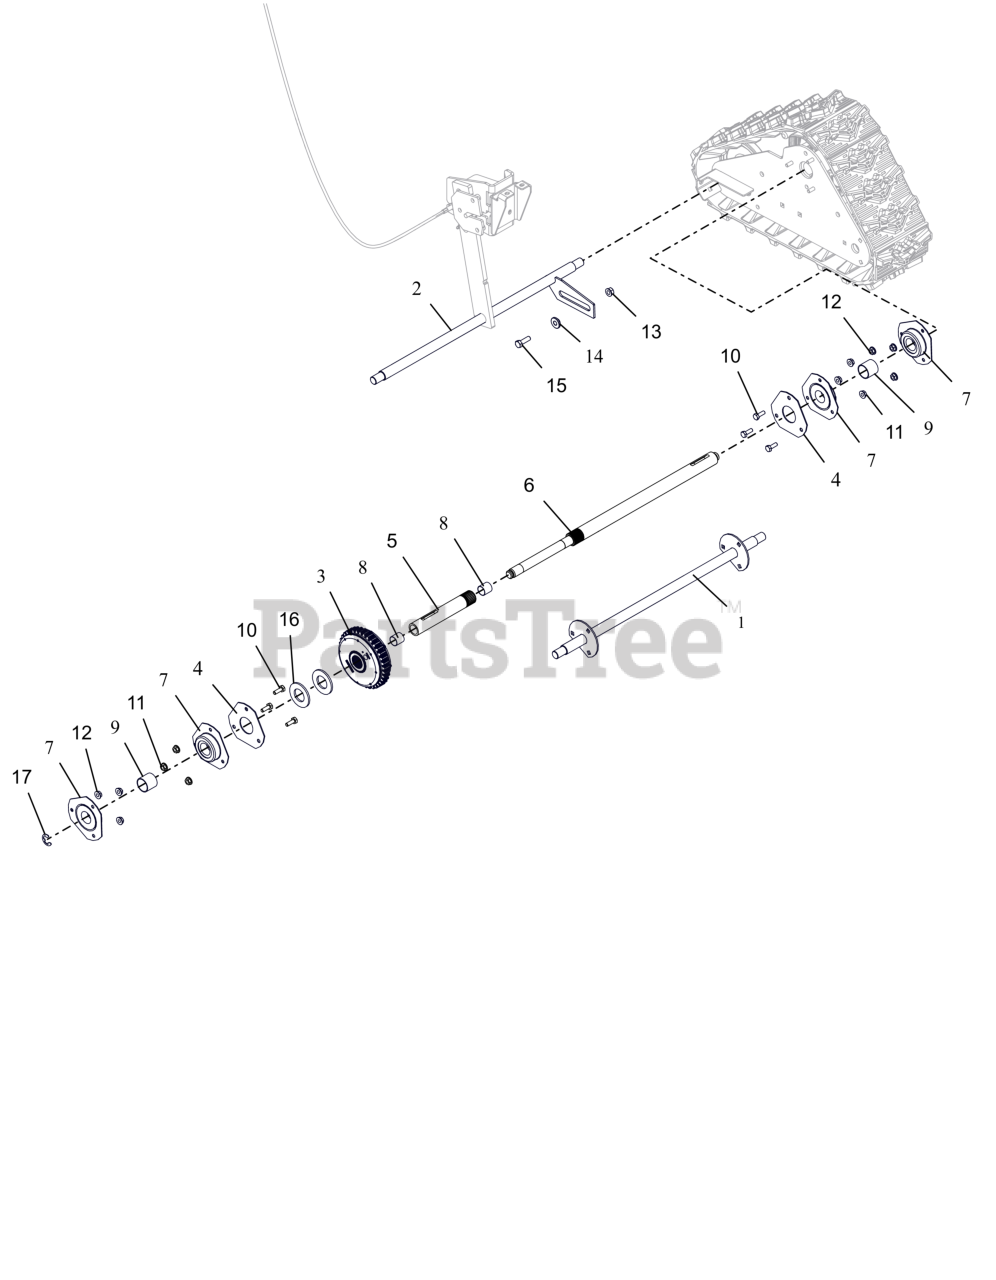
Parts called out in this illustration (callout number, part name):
1	AXLE, FRONT - PRO
2	AXLE, REAR - PRO TRACK
3	DIFFERENTIAL, AUTOMATIC
4	PLATE, BEARING SPACER
5	AXLE, SHORT-W/BUSHINGS
6	AXLE, LONG-TRACK DIFFERENTIAL
7	BRG-FLG 1.003/1.000 3 BOLT
8	BSHG-SLV .706X.764X.75 BRZ
9	BSHG-SLV, 1.012X1.125X1.00
10	BLT, HEX .25-20X.75 G5 ZCC
11	NUT-LK-CTR-FLG .25-20 ZC120
12	NUT-LK-TOP-FLG .250-20 GF ZCC
13	NUT-LK-TOP-FLG .312-18 GF ZCC
14	BSHG-FLG .325X.499X.3X.875
15	BLT,HEX .31-18X1.00 G5 ZCC
16	WSHR, FLT 1.062X2.000X.134 ZCC
17	RG-RTNG-EXT .625X.042
